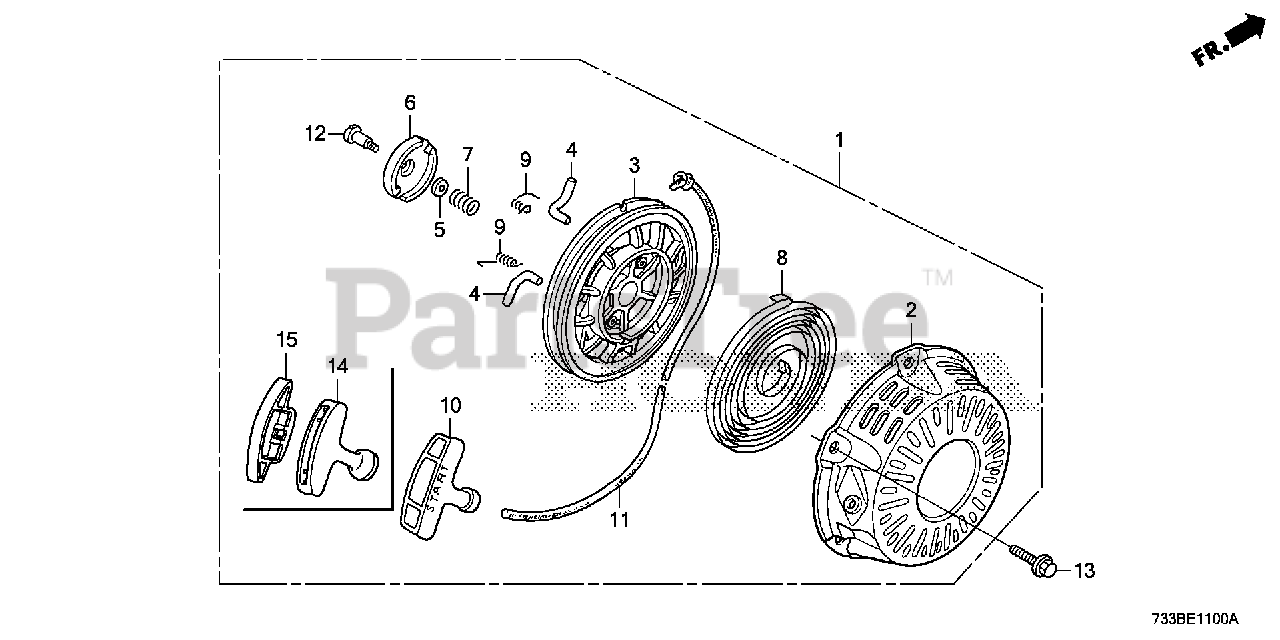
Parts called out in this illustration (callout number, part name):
1	STARTER ASSY., RECOIL *R280* (POWER RED)
2	CASE, RECOIL STARTER *R280* (POWER RED)
3	REEL, RECOIL STARTER (BLACK)
3	REEL, RECOIL STARTER
4	RATCHET, STARTER
5	PLATE, FRICTION
6	GUIDE, RATCHET
7	SPRING, FRICTION
8	SPRING, RECOIL STARTER
9	SPRING, RETURN
10	GRIP, STARTER
10	KNOB, RECOIL SRARTER
11	ROPE, RECOIL STARTER
12	SCREW, SETTING
13	BOLT, FLANGE (6X10)
